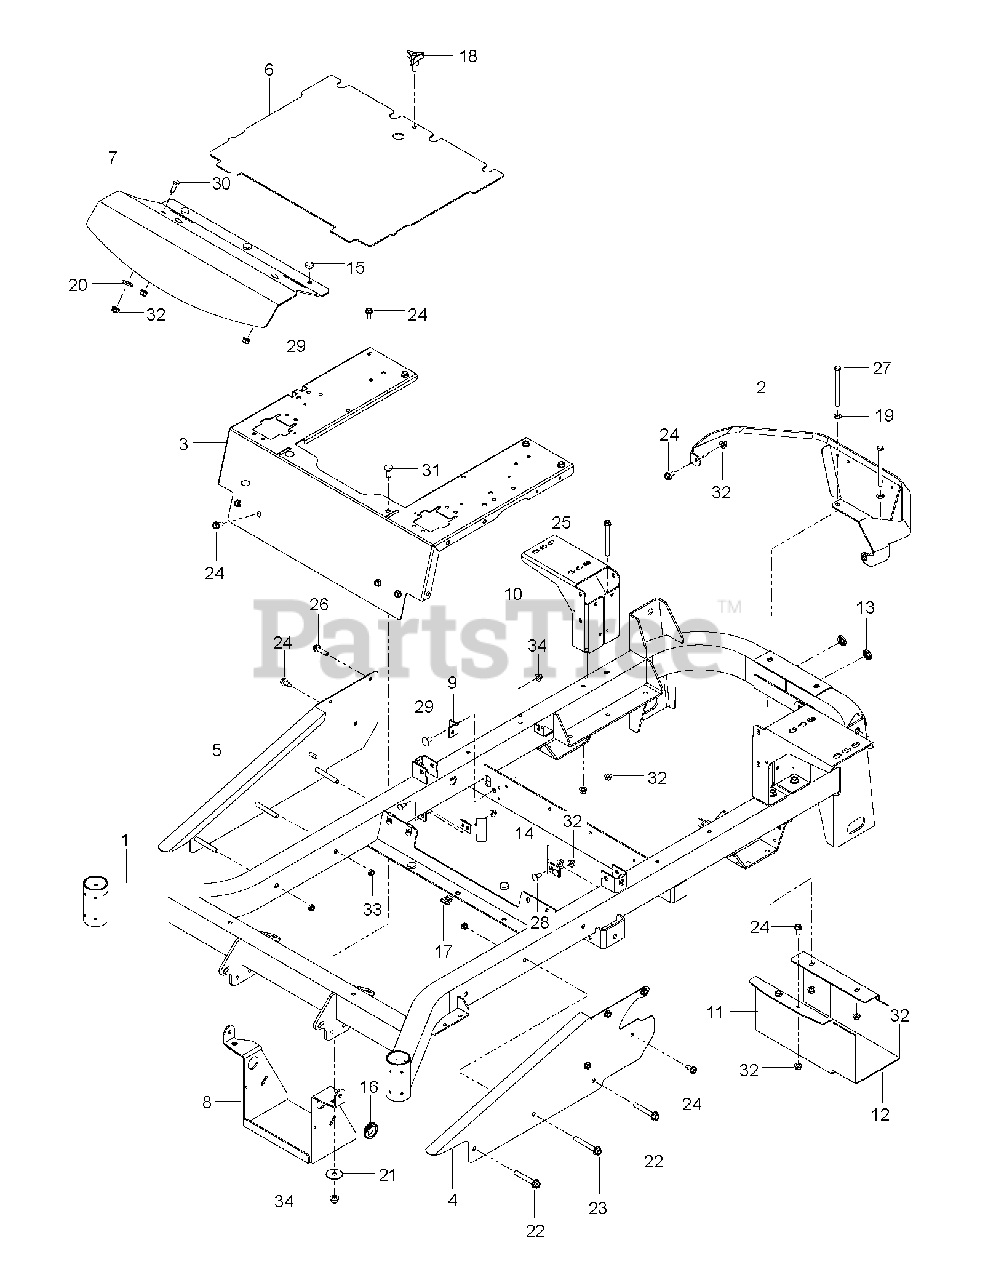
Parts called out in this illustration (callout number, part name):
1	KIT.FRAME.W/DECALS.X668
2	GUARD.PNT.REAR.MZ.GRAY
3	SUPPORT.PNT.SEAT.CONTROL.ORNG
4	SIDE.LT.ORANGE
5	SIDE.RT.ORANGE
6	PLATE, FLOOR W/DECALS
7	PLATE, FOOTREST
8	BRACKET.PNT.BATTERY.BLK
9	BRACKET.DAMPENER.BLACK
10	MOUNT, TANK, ZT BLK
11	SHIELD.MUFFLER.BLACK
12	HEAT SHIELD
13	CAP.PLUG.BP-1.BLACK
14	STOP, DECK, EZ+
15	GROMMET, BUMPER
16	RUBBER GROMMET
17	U-CLIP 5/16-18 NUT RETAINER
18	KNOB W/STUD
19	WASHER
20	WASHER 1/2" FLAT
21	WASHER.13/32X1-1/2X16GA
22	HHFS 3/8-16 X 2.5 GR 5 ZD
23	HHFS 3/8-16 X 2-3/4 GR5 ZD
24	HHFS 5/16-18 X 3/4
25	BOLT.HEX.FLNG.5/16-18X3.75
26	HHFS 5/16-18 X 1.25 TPBLT GD 5
27	HCS 5/16C X 4
28	BOLT 5/16C X 3/4" CARRIAGE
29	RHSNB 3/8-16 X 3/4 GR 5 BLK ZN
30	RHSNB 5/16C X 1
31	RHSNB 3/8C X 1
32	5/16-18 NYLOC FLANGE NUT
33	NUT HEX 3/8-16 NYLON, THIN
34	NUT 3/8-16 HEX FLG NYLOC ZD
